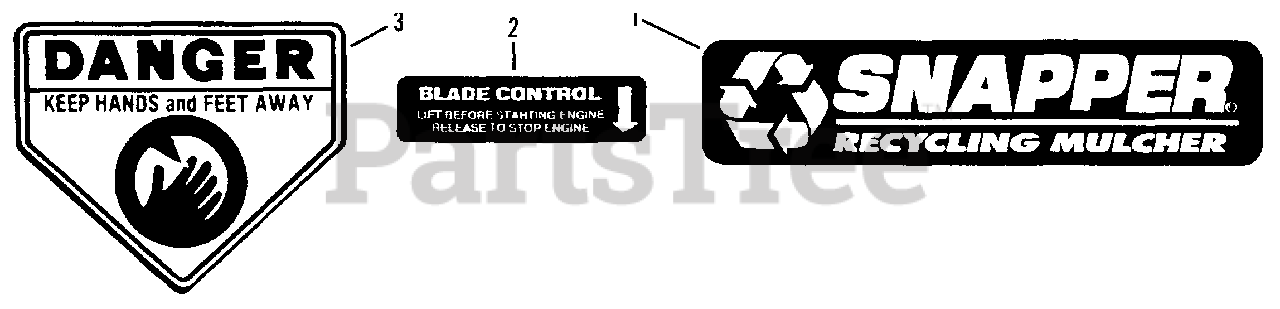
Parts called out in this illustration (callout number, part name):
1	LOGO, SNAPPER (Recycling / Mulching)
2	DECAL, Blade Control
3	DECAL, Danger
